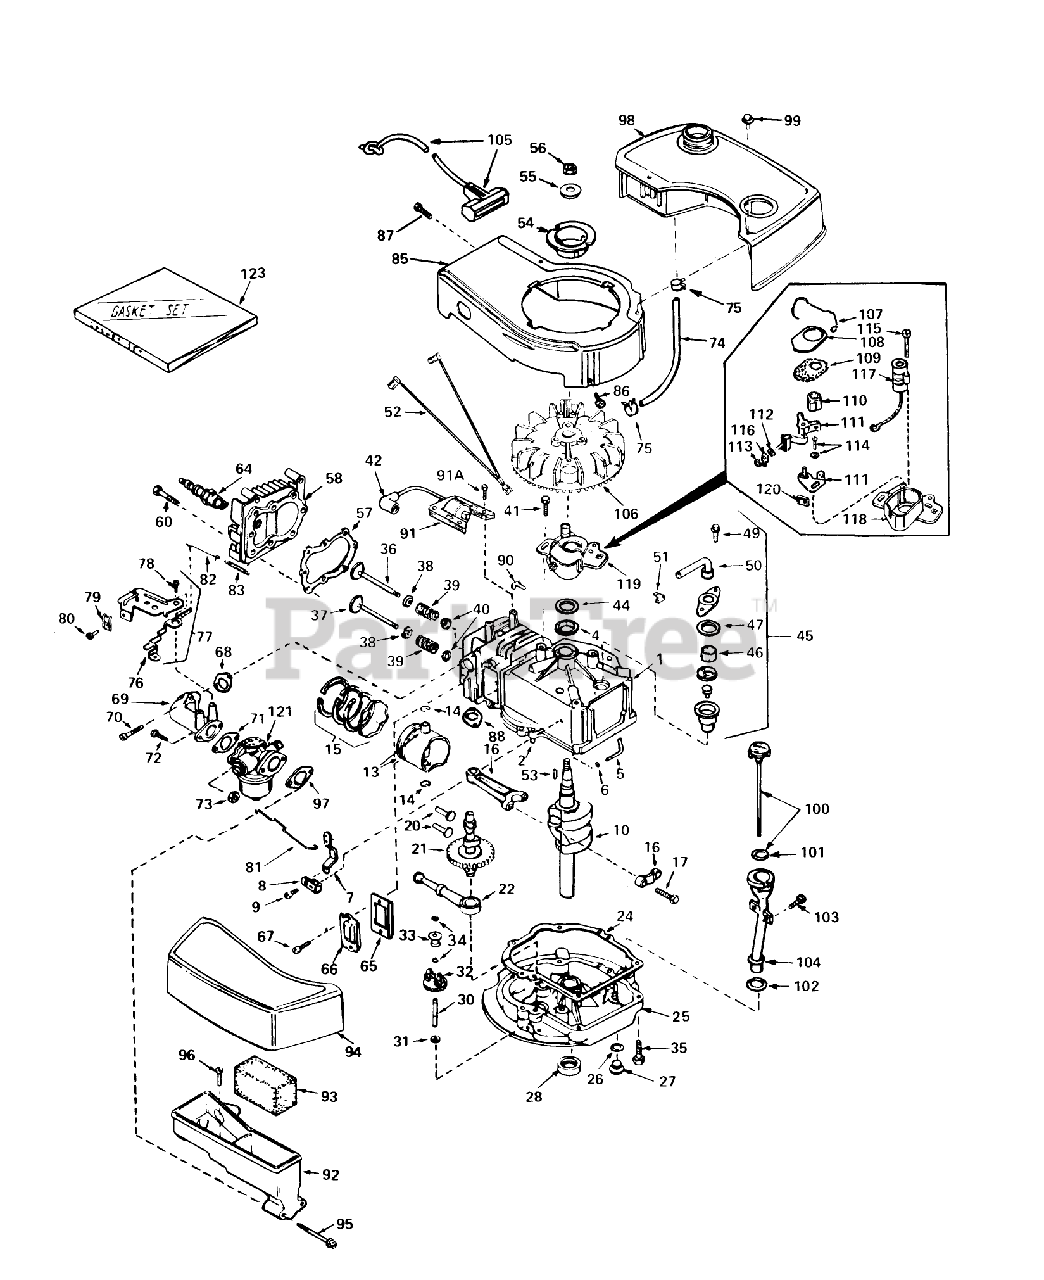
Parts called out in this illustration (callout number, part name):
1	Cyiinder Assy. (Incl. Ref. #2, 4 105)
2	Pin-Dowel
4	Seal-Oil
5	Rod, Governor (Incl. No. 36)
6	Washer-Flat
7	Governor Lever
8	Clamp-Lever, Governor
9	Screw
10	Crankshaft
13	Piston, Pin Ring Assy. (Incl.Ref. #14 15)(Std.)
13	Piston, Pin Ring Assy. (Incl. #14 15)(.010 oversize)
13	Piston, Pin Ring Assy. (Incl.Ref. #14 15) (.020 oversize)
14	Ring-Retaining, Piston Pin
15	Ring Set Piston (Std.)
15	Ring Set Piston (.010 Oversize)
15	Ring Set Piston (.020 Oversize)
16	Rod Assy., Connecting (Incl. Ref. #17)
17	Bolt-Rod, Connecting
20	Lifter-Valve
21	Camshaft(Mech.Comp. Release)
22	Oil Pump ASM
24	Gasket, Mounting
25	Flange Assy., Mounting (Incl. Ref. #26thru 30)
26	Gasket-Oil Drain
27	Plug Oil Drain
28	Seal Oil
30	Shaft-Governor
31	Washer-Flat
32	Governor Gear ASM
33	Spool-Governor
34	Ring-Retaining
35	Screw (1/4-20 x 1-1/4)
36	Valve, Intake (Incl. Ref. #38, 39 40) (Std.)
36	Valve, Exhaust (1/32" Oversize) (Incl. Nos. 8, 9 10)
37	Valve, Exhaust (Standard) (Incl. Nos. 8, 9 10)
37	Valve, Exhaust (1/32" Oversize) (Incl. Nos. 8, 9 10)
38	Cap-Upper Valve Spring
39	Spring-Valve
40	Cap-Valve, Spring
41	Screw
42	Cover-Spark Plug
44	Gasket, Stator
45	Breather Assy. (Incl. Ref. #46, 47, 49, 50 51 )
46	Element-Breather
47	Gasket-Breather
49	Screw, Hex Hd. w/Conical
50	Tube, Breaker
51	Clip, Breather
52	Wire Ground
53	682488 LB GRASS HI-
54	Hub-Starter
55	Washer-Belleville
56	Nut-Flywheel
57	63573 GIL 42 SNWTHW
58	Head-Cylinder
60	Screw (5/16-18x1-1/2)
64	Plug, Spark (J17LM or equiv.)
64	Plug, Spark (Champion RCJ-8)
65	Gasket-Breather
66	Cover-Valve
67	Screw
68	Gasket, Intake
69	Pipe, Intake
70	Screw (1/4-20 x 1)
71	Gasket-Carburetor
73	Nut and Lock Washer (1/4-28)
74	Line-Fuel
75	Clamp-Line, Fuel
76	Lever Control
77	Control Assy., Speed (Incl. Nos, 76, 78 89)
78	Screw, Hex Washer Hd Shoulder Self-Tap
79	Conduit
80	Screw (10-32 x 3/8)
81	Link-Throttle
82	Link Governor Spring
83	Spring Governor
85	Housing Blower
86	Nut-Jam
87	Screw (10-24 x 9/16)
88	Gasket Exhaust
90	Clip-Wire
91	Lamination Coil Assy. (Incl. No. 42)
91A	Screw
92	Body Air Cleaner
93	Filer, Air
94	Cove, Air Cleaner
95	Screw Fil Hd.
96	Screw, Hex Hd.
97	Gasket-Air Cleaner
98	Tank, Fuel
99	Screw (10-32 x 35/64)
100	Dipstick, Oil (Incl. Ref. #101)(Twist Lock)
101	O-Ring
102	Gasket
103	Screw (10-32 x 1/2)
104	Tube-Oil Fill
105	Rope Assy., Starter
106	FIywheel
107	Spring Breaker Box
108	Cover-Dust
109	Gasket-Dust Cover
110	Cam-Breaker
111	Breaker Assy.
112	Washer
113	DECAL
114	Breaker Screw
115	Condenser Screw
116	Terminal, Ground
117	Condenser
118	Stator Plate
119	Stator Assembly (Incl. Ref. #107, 111-118 120)
120	Felt,Cam Wiper
121	Carburetor (Incl. Ref. #71 )
123	53024/VAR.16HP O/P
